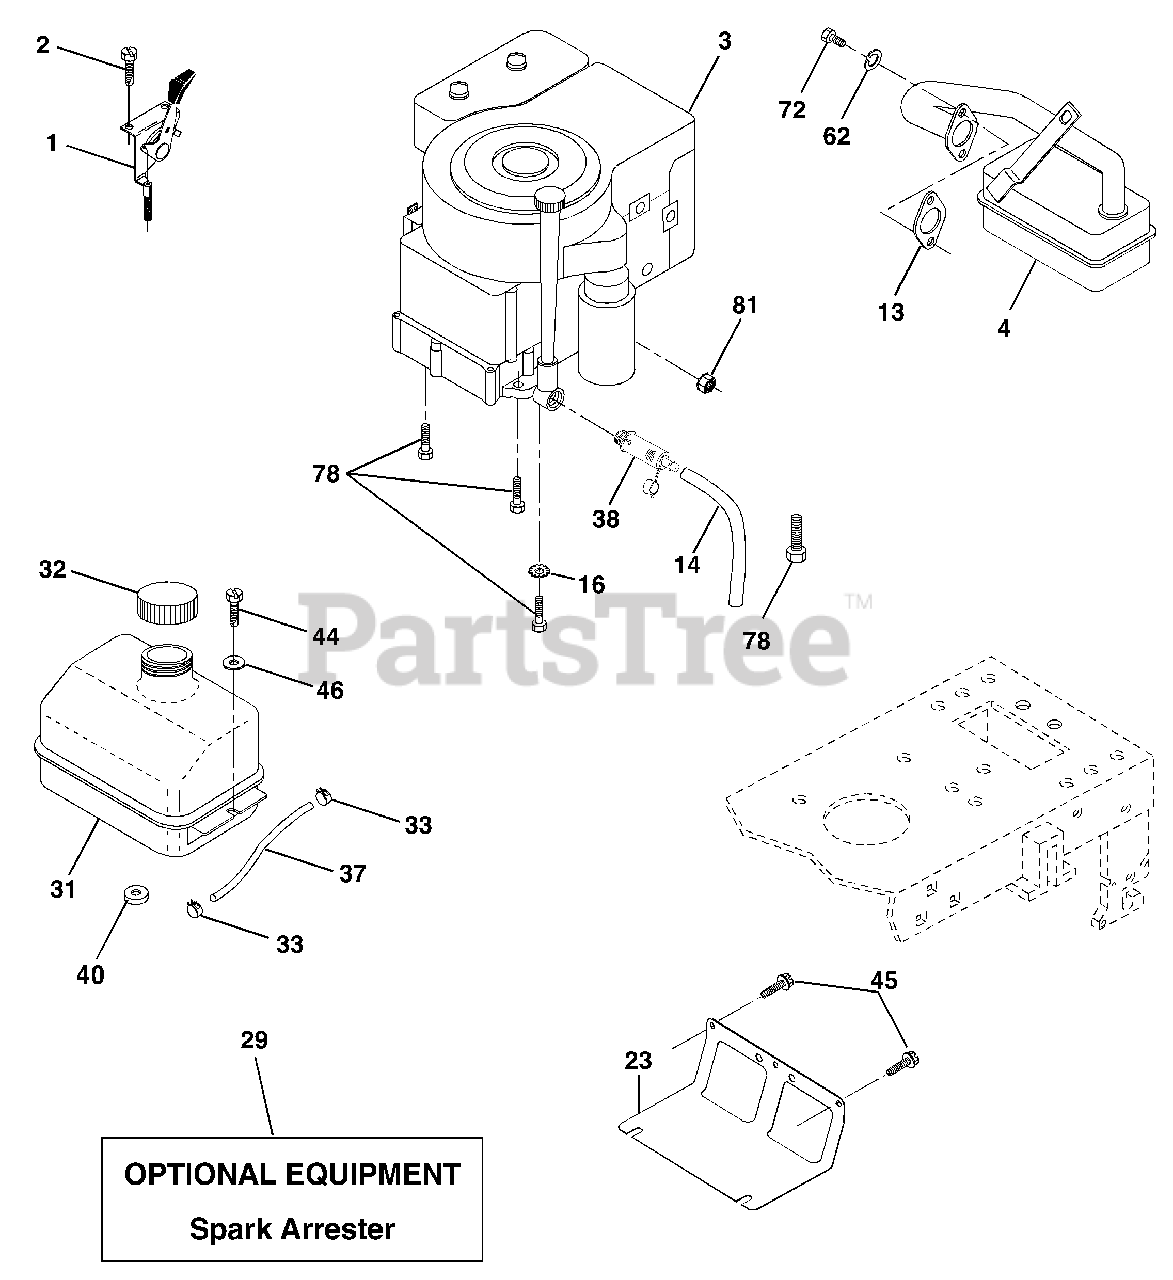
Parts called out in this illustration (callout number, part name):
1	Control Throt /Ch 23.5 Lh Flag
2	Screw Hex Thd Cut 1/4-20x5/8 T
4	Muffler Exhaust B&S Lt
13	Gasket 1 313 Id Tin Plated
14	Tube Drain Oil Easy
16	Washer Lock Ext Tooth 3/8
23	Shield Browning/Debris Guard
29	Arrestor Spark
31	Tank Fuel 1 25 Fr
32	Cap Asm Fuel W/sym Vented
33	Clamp Hose Blk
37	Line Fuel 20"
38	Plug Oil Drain
40	Bushing Snap Nyl Blk Fuel Line
44	Screw Hexwsh Thdrol 1/4-20x3/4
45	Screw Hex Wsh Thdrol 3/8-16
46	Washer 9/32 X 7/8 X 16ga
62	Washer Lock Hvy Hlcl Spr 5/16
72	Screw Hexhd Cap 5/16-18x3/4
78	Screw Thdrol 3/8-16x1-1/4
81	Nut Keps Hex 1/4-20 Unc
